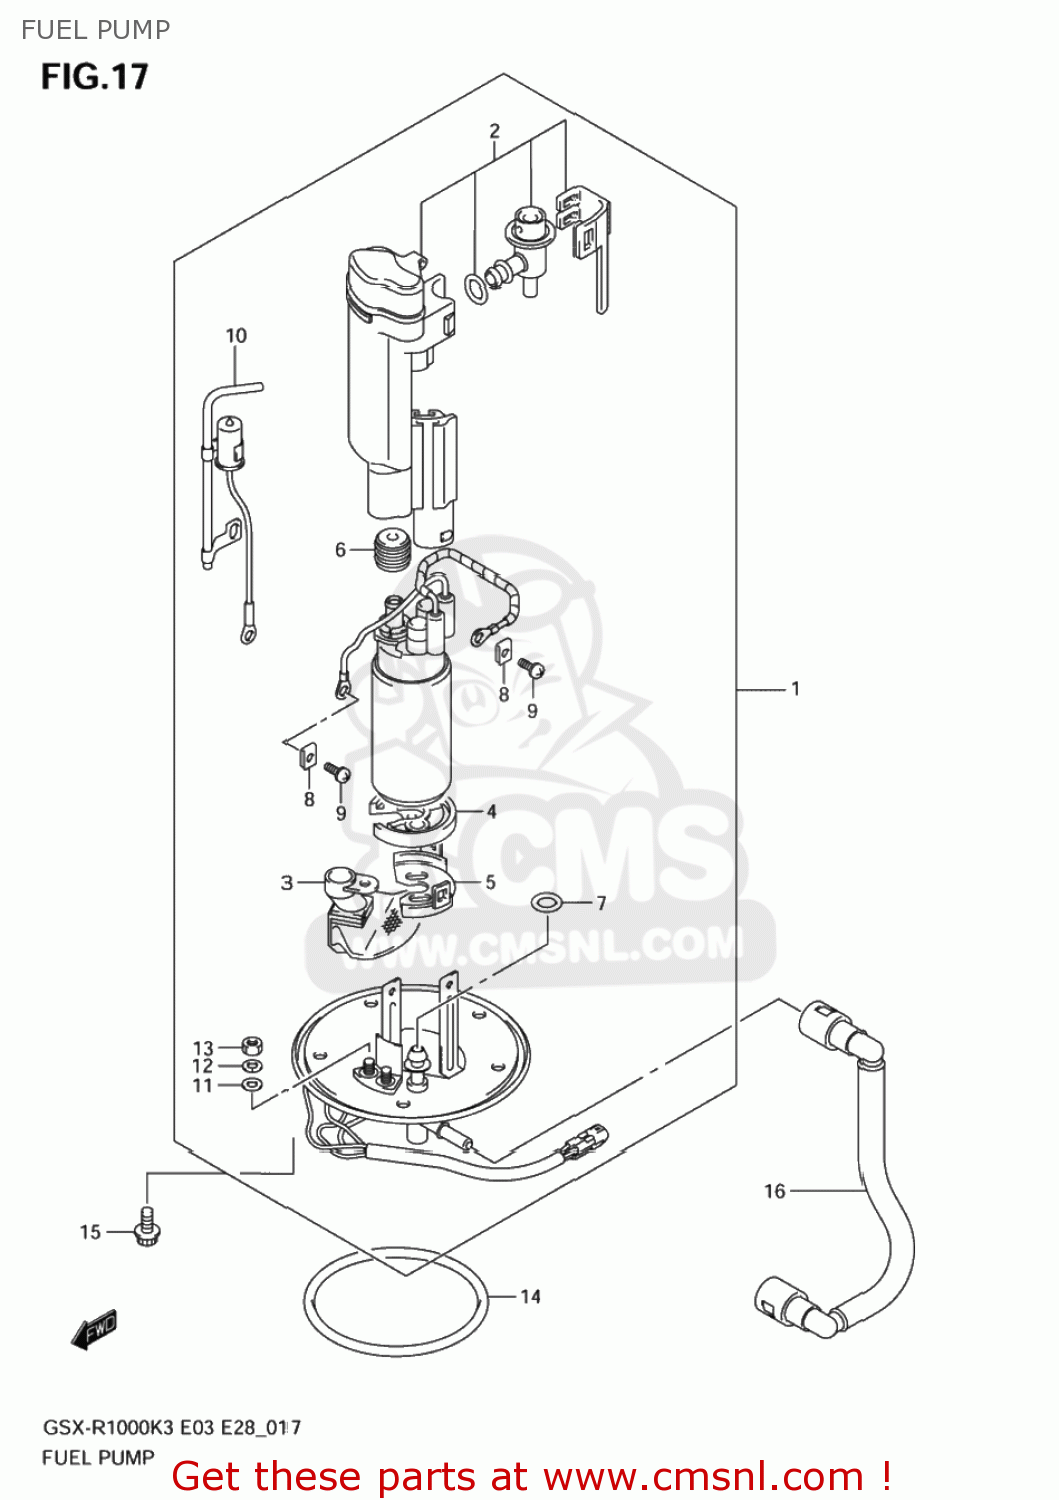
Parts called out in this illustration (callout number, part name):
1	PUMP ASSY,FUEL
2	FILTER ASSY,FUEL
3	STRAINER,FUEL PUMP
4	CUSHION
5	HOLDER,FUEL PUMP
6	BUSH,FUEL PUMP
7	O RING
8	NUT
9	SCREW
10	THERMISTOR
11	WASHER
12	WASHER,SPRING
13	NUT
14	O RING,FUEL PUMP
15	BOLT
16	HOSE,FUEL
